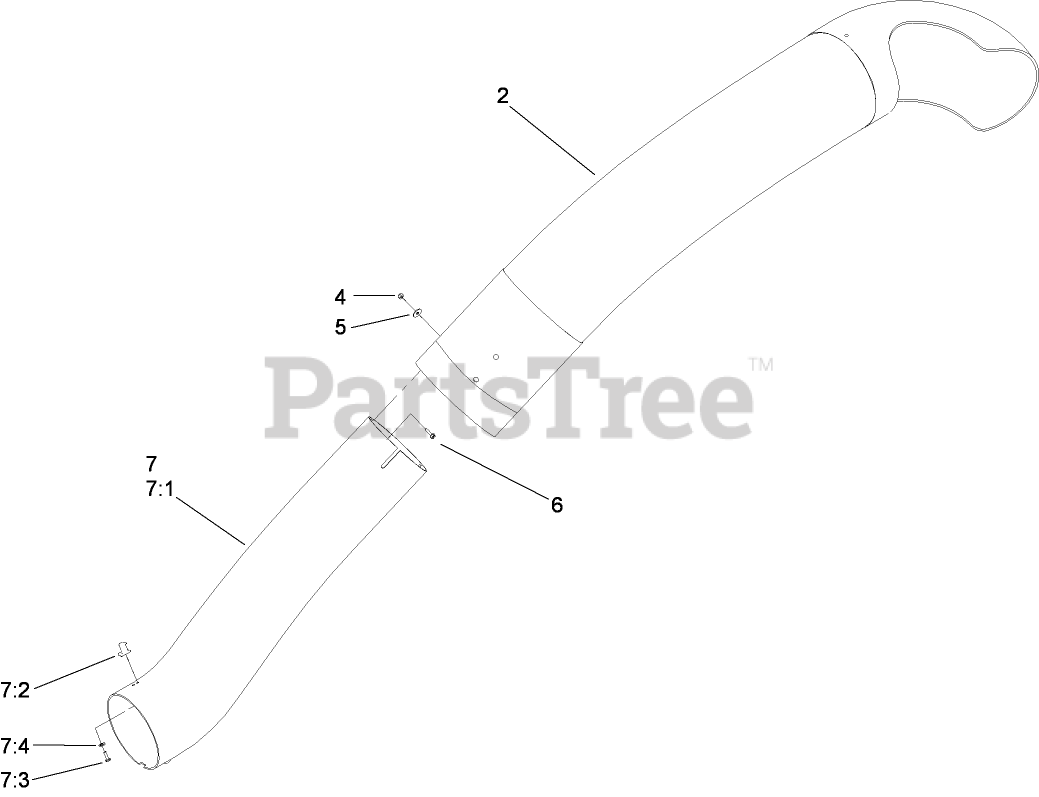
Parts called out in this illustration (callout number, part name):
2	TUBE-UPPER
4	NUT-LOCK, NI
5	WASHER-FLAT
6	SCREW-HWH
7	LOWER TUBE ASM
7:1	TUBE-LONG, LOWER
7:2	LATCH-KEEPER
7:3	SCREW-PPH
7:4	WASHER-FLAT
